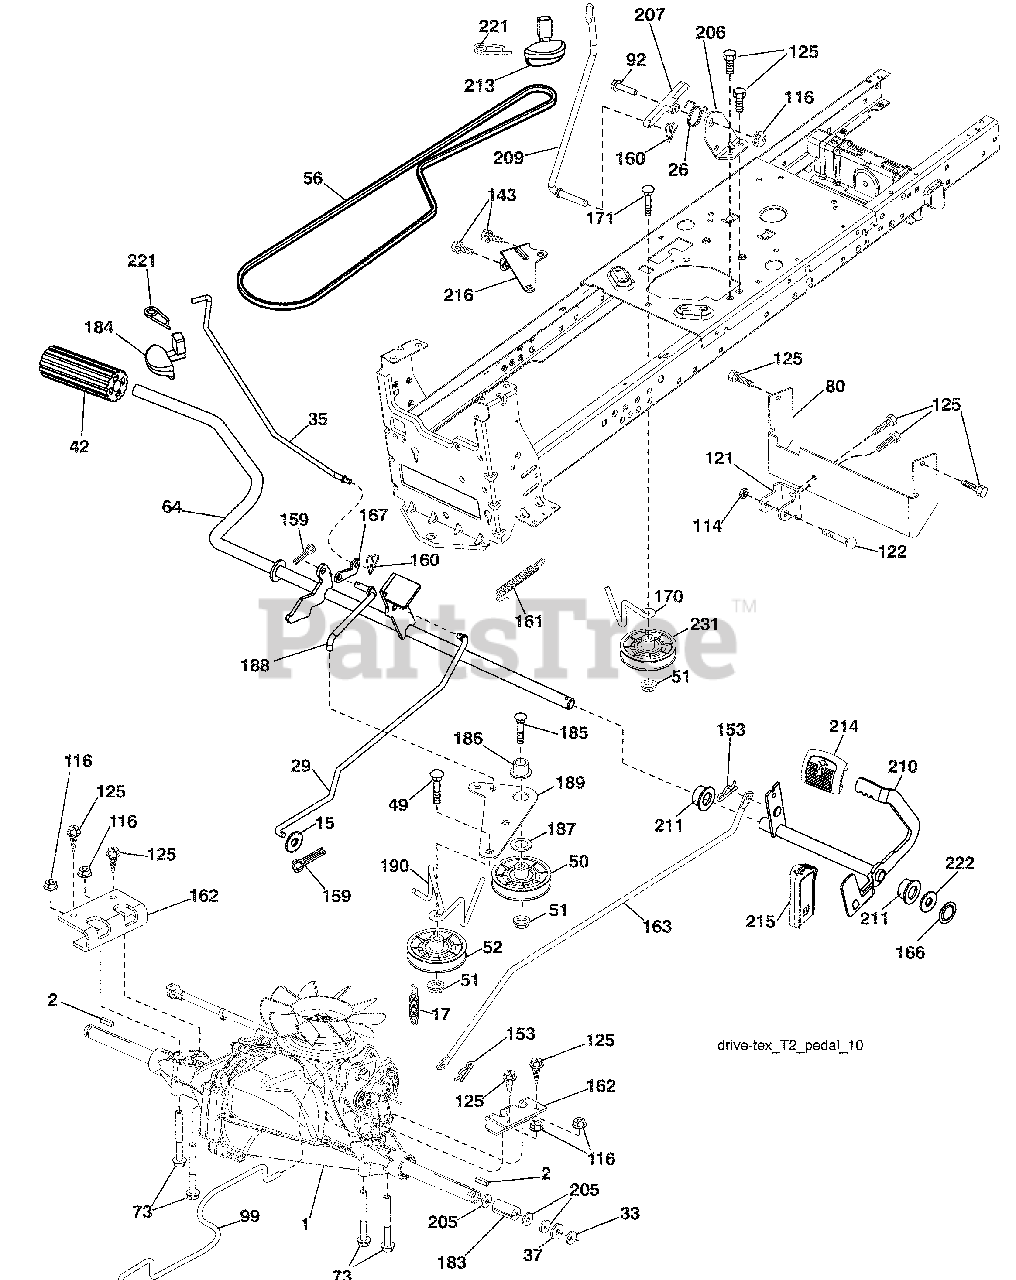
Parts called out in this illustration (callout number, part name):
2	Key Square
15	Washer 13/32 x 13/16 x 16 Ga.
17	Spring, Brake
26	Spring Return Cruise
29	Rod, Brake
35	Rod, Brake, Park
37	Washer 25/32 x 1-1/4 x 16 Ga.
42	Cover, Foot Pedal
50	Pulley Idler Flat
51	Lock Nut 3/8-16
52	Idler V-Groove 910" Offset
56	V-Belt, Drive
64	Shaft Asm. Pedal Brake Control
73	Bolt Hex 5/16-18 Gr. 5
80	Strap Torque
92	Bolt Fin Hex 5/16-18 unc x 1.25
99	Rod Spring Bypass
114	Nut Lock HX W/Ins 5/16-18
116	Nut Lock Hex Flange 5/16-18
121	Bracket Strap Torque
122	Bolt 5/16-18 x 2.50
125	Screw 5/16-18 x 3/4
143	Screw 5/16-18 x 1/2
153	Retainer Spring 1"
159	Pin Cotter 1/8 x 3/4
160	Retainer Clip
161	Spring, Return, Clutch
162	Adapter Transaxle
163	Rod Control
166	Nut Push
167	Latch Brake Parking
170	Keeper V-Idler
183	Spacer Axle
184	Handle Parking Brake
186	Spacer Retainer
187	Washer
188	Link Clutch Ground Drive
189	Bellcrank Ground Drive
190	Keeper Bellcrank Ground Drive
205	Washer 25/32 x 1-5/8 x 16 Ga.
206	Bracket Mount Latch Cruise
207	Latch Control Cruise
208	Gear Sector Control Cruise
209	Rod Control Cruise
210	Rocker Asm. Pedal Control
211	Bearing Nylon
213	Knob Control Cruise
214	Pedal Forward
215	Pedal Reverse
216	Bracket Pulley Idler
221	Retainer Spring Clip Handle
222	Washer 21/32 x 1-1/4 10 Ga.
231	Idler V-Groove 1.688" Offset
